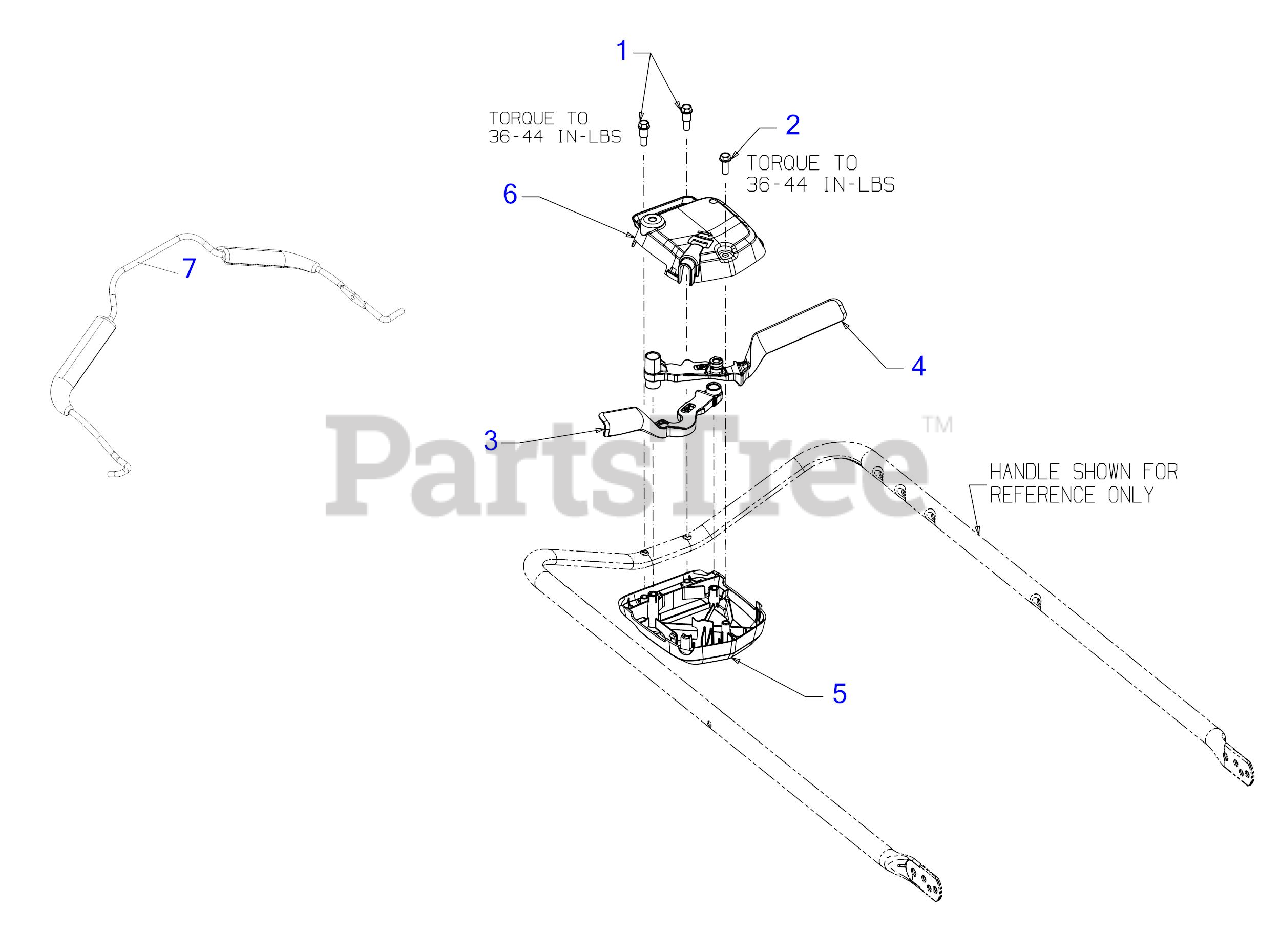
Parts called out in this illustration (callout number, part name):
1	SHOULDER SCREW 1/4-15 x .970
2	SCREW 1/4-15 x .750
3	CONTROL LEVER (LH)
4	CONTROL LEVER (RH)
5	UPPER CONTROL HOUSING
6	LOWER CONTROL HOUSING
7	OPERATOR BAIL ASSEMBLY
